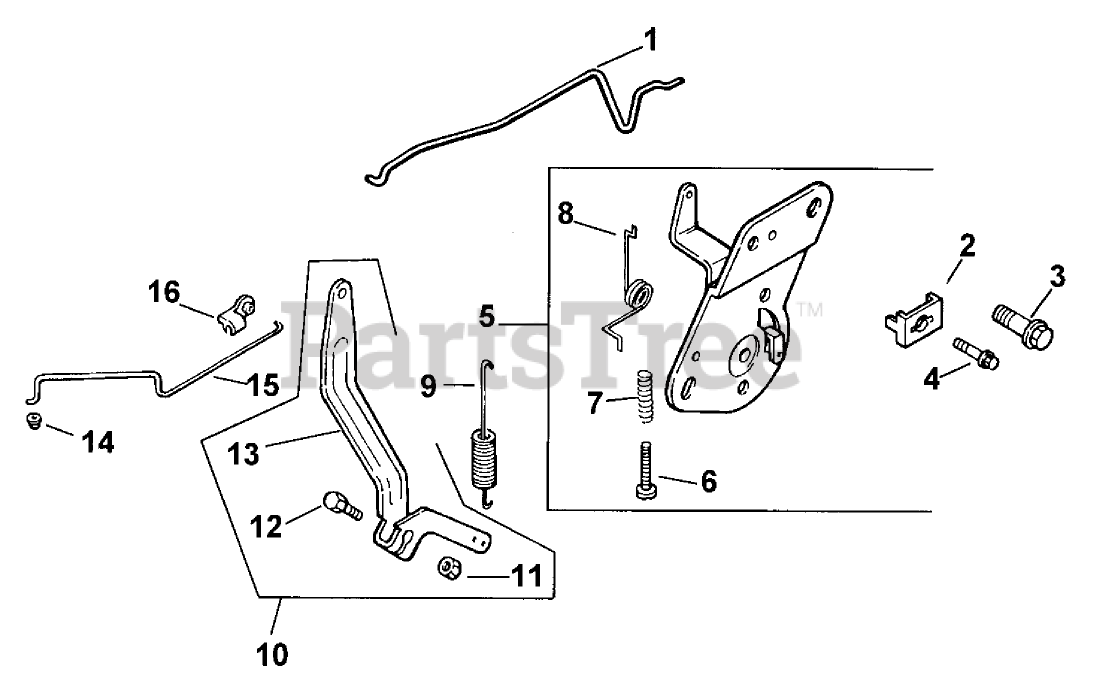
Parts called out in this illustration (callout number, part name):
1	Linkage Choke
2	Clamp
3	Screw Socket
4	Screw
5	Control-Speed
6	Screw
7	Spring
8	Spring Choke
9	Spring-Governor
10	Kit-Governor Lever (Incl. Ref.#11-13)
11	Nut
12	Bolt
13	Lever-Governor
14	Bushing-Linkage
15	Linkage-Throttle
16	Bushing-Linkage
